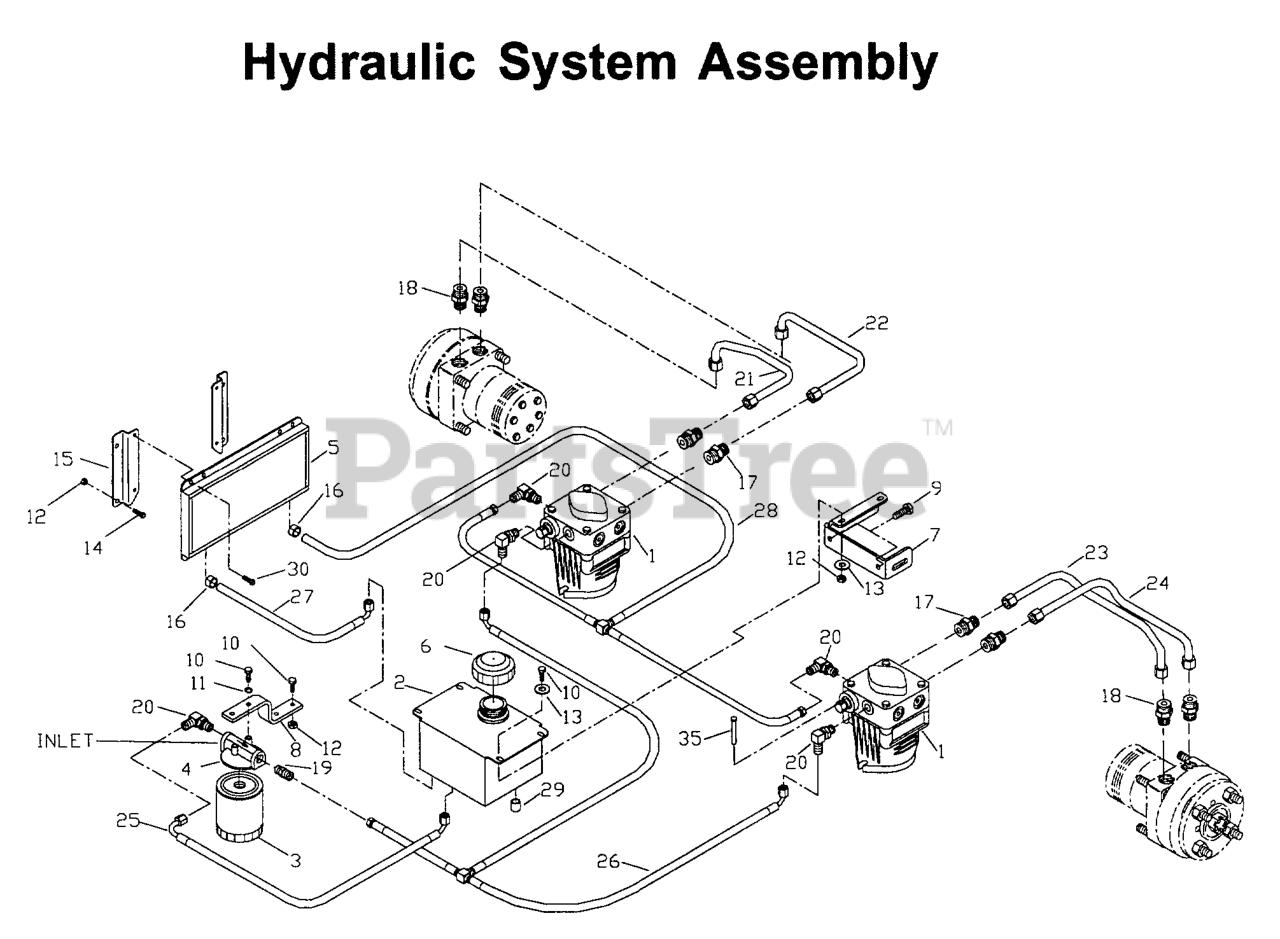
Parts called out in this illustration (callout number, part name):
1	PUMP
3	FILTER, OIL, NO VALVE
4	FILTER HEAD
6	HYDRAULIC CAP
7	TANK MOUNT LT
8	FILTER MOUNT
9	HCS 5/16C X 3/4
10	HCS 1/4C X 3/4 HCS
11	LOCKWASHER 1/4"
12	NUT 1/4C CENTERLOCK
13	WASHER 1/4 FLAT
14	HCS 1/4C X 2
15	FRONT COOLER BRKT
16	HOSE CLAMP T-1865
17	FITTING, STRAIGHT F6400-8-8-0
19	STRAIGHT FITG
20	ELBOW, F6801-6-6-0 90 DEGREE
21	RUBBER HYDRAULIC HOSE (1)
22	RUBBER HYDRAULIC HOSE (1)
23	RUBBER HYDRAULIC HOSE (1)
24	RUBBER HYDRAULIC HOSE (1)
29	NUT 9/16-18 JIC CAP
30	HEX CAP SCREW 1/4
539105026	TANK MOUNT RT
539105767	COOLER BRACKET
